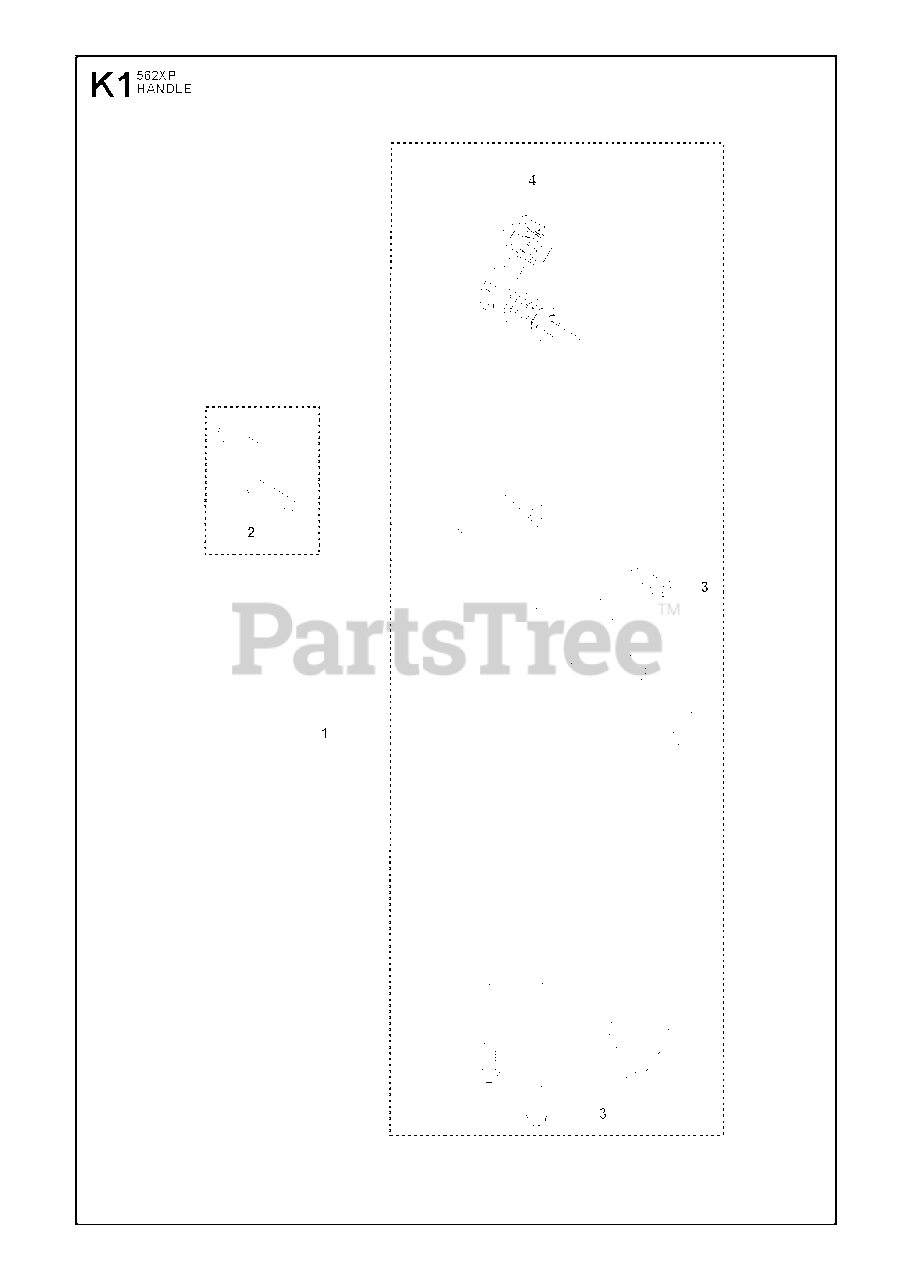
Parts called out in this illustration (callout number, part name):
1	FRONT HANDLE
2	SCREW
3	SCREW IHSCFT
4	ANTIVIBRATION ELEMENT
